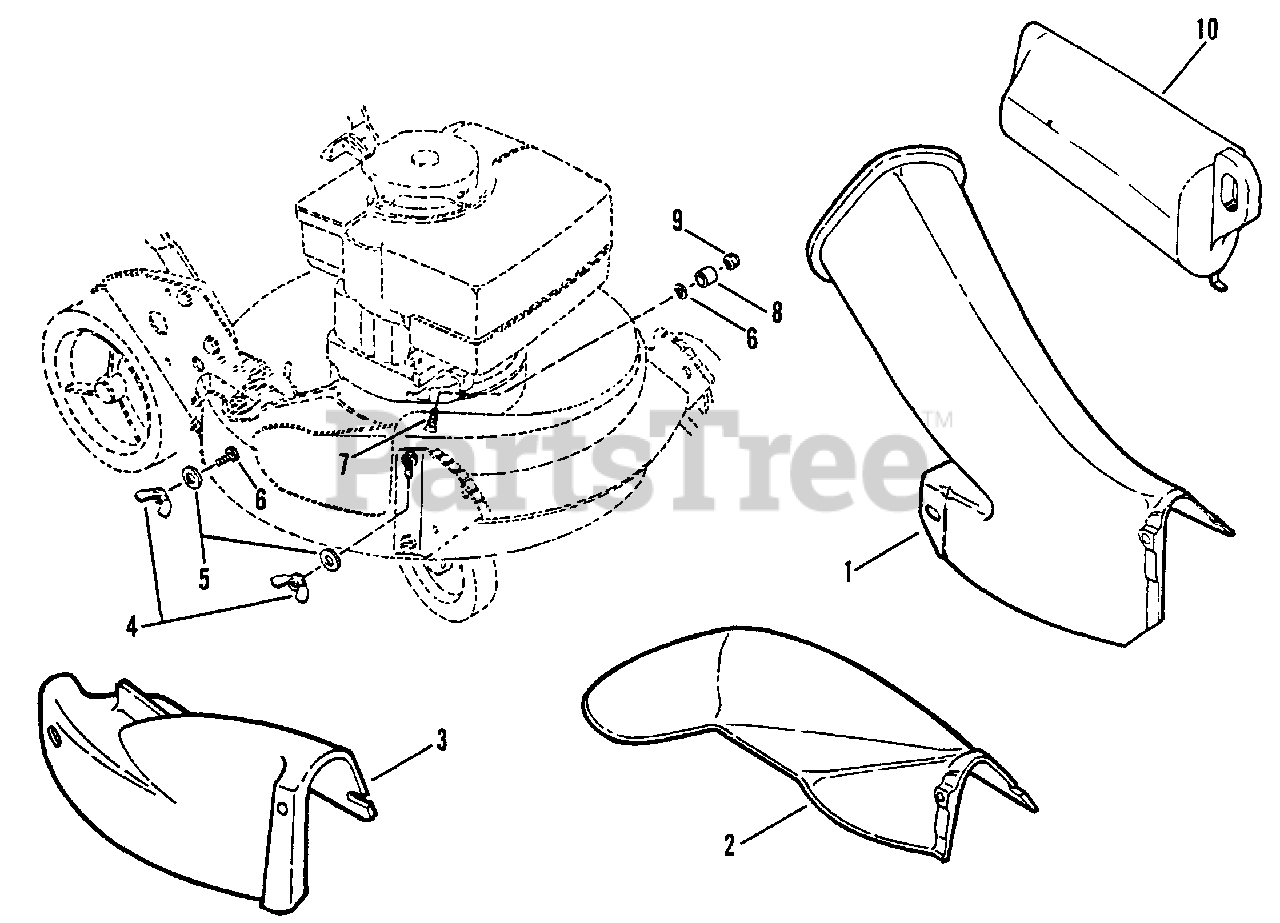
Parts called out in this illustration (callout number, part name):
1	ADAPTER, Grass Bag
2	KIT, Side Chute
3	COVER, Mulching (21" Cutting Deck)
4	WING-NUT, 5/16-18 Nyloc
5	WASHER, 3/8" Flat
6	RETAINER, 5/16 Bolt
7	BOLT, 5/16-18 x 3/4 Short Neck Carriage, Grade 5
8	SPACER
9	NUT, 5/16-18 Hex Flange, Center Lock
10	PLUG, Chute Adapter
